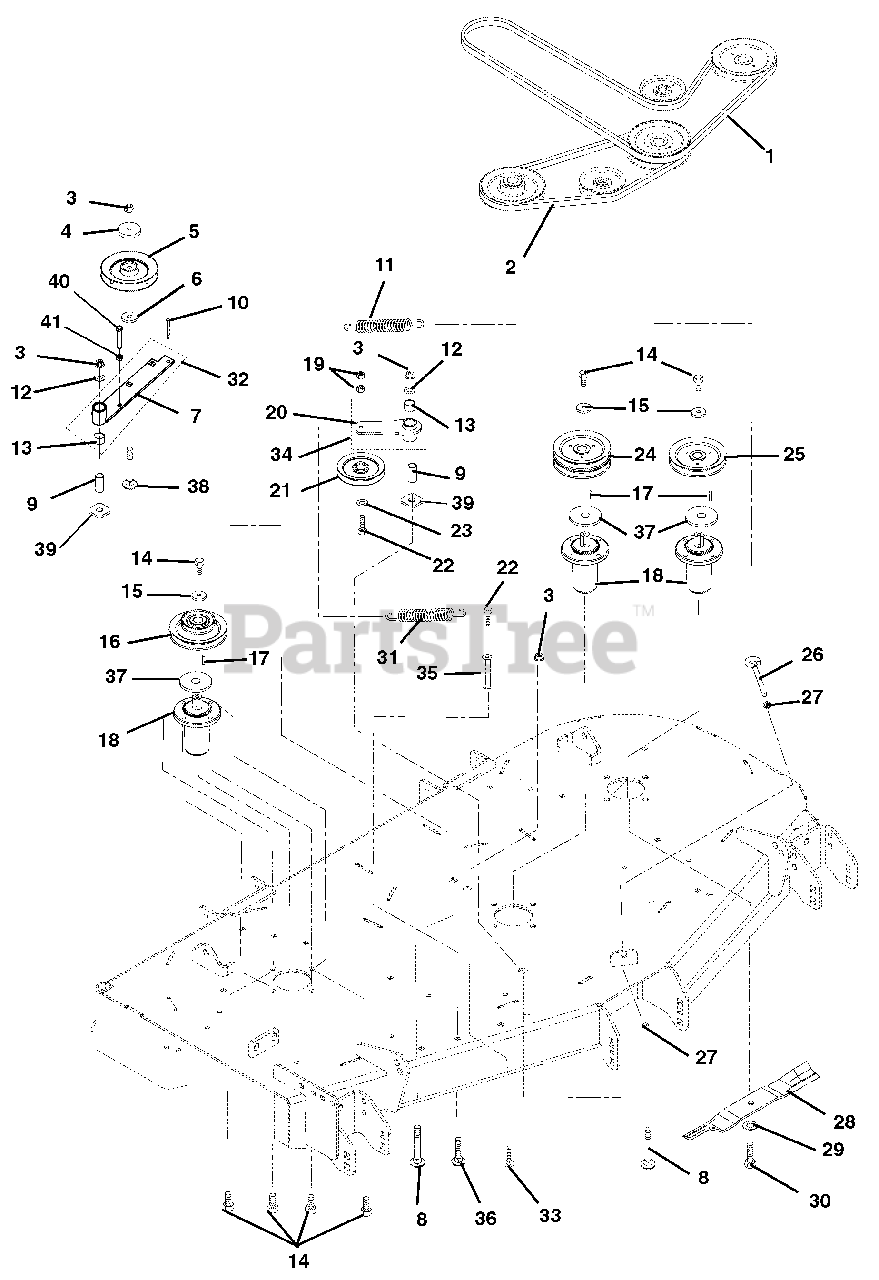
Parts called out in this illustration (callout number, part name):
1	Belt, 118.00" Long, PTO Drive Hex (991026, 032)
2	V-Belt, 51.18" Long Cog B-Section (991026, 027, 029, 032)
3	Nut, .50-13 Nyloc Flange
4	Cap, Idler Bearing Sealing
5	Pulley, V 6.0 x 5.00 ID Single Bearing (Serial Numbers 6500 and up)
6	Bushing, Spacer .502 x .997 x .50
7	Weldment, Idler Arm
8	Bolt, Round Head Square Neck .50-13 x 3.50
9	Bushing, Spacer .502 x .997 x 2.03 (991026 — serial no. 7690 & up; 991027 – serial no. 7790 & up; 991028 – serial no. 8107 &
10	Bolt, Shoulder EP .38-16 x .30 Hex
11	Spring, Extension (Deck Idler)
12	Washer, Flat Steel .531x 1.250 x.100
13	Bushing, 1.00 x 1.25 x 1.936
14	Bolt, Hex .38-16 x 1.00
15	Washer, Flat Steel .406 x 1.50 x .245
16	Sheave, Double, 1" I.D. x 5.44" O.D. x 3.50" O.D. (991026, 027, 029, 032)
17	Key, Square .25 x .25 x 1 RC 40-50
18	Spindle Assembly
19	Nut, Locking-Center .38-16
20	Weldment, Idler Arm
21	Sheave, .38" ID x 5" OD
22	Bolt, Hex .38-16 x 2.25
23	Washer, Flat Steel .406 x .812 x .065
24	Sheave, Double 1" I.D. x 5.44" O.D. (991026, 027, 029, 032)
25	Sheave, Single 1" I.D. x 5.44" O.D. (991026, 027, 029, 032)
26	Bolt, .38-16 x 4.00 .62 Diameter Eye
27	Nut, Hex, Jam .375-16
28	Blade, Mower, 44 in. & 48 in. Decks (991026, 027, 029, 032)
29	Washer, Bellville .63 x 1.625 x.14
30	Bolt, Hex .62-18 x 1.75 Grade 8
31	Spring, Extension
32	Assembly, PTO Idler Pivot Arm (Includes item # 7 and item # 13)
33	Bolt, Round Head Square Neck .50-13 x 1.5, Full Thread, Grade 5
34	Assembly, Idler Pivot Arm (Includes item # 13 and item # 20) (991026 – serial no. 7690 & up; 991027 – serial no. 7790 & up; 99
35	Nut, Coupling .375-16 x 1.75
36	Bolt, Round Head Square Neck .38-16 x 1.00
37	Slinger, Dust
38	Bolt, Round Head, Square Neck .50-13 x 3.00, Grade 5
39	Washer, Flat .640 x 1.75 x .250
40	Bolt, Hex .38-16 x 2.75 Grade 5
41	Nut, Hex .38-1
